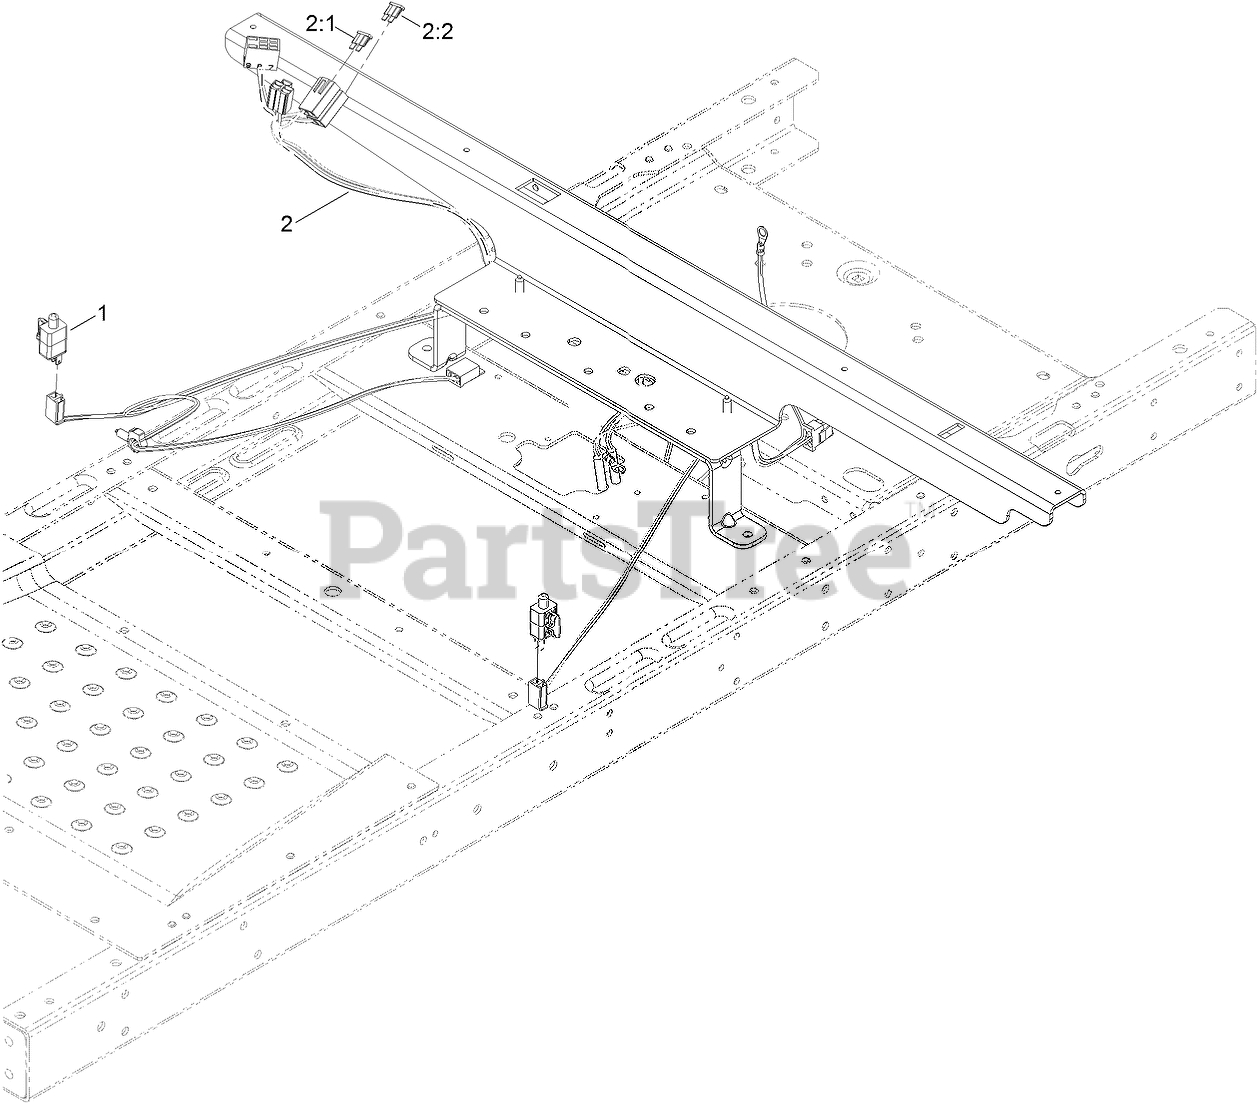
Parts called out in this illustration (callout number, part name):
1	SWITCH
2	HARNESS-WIRE
2:1	FUSE-BLADE, 30 AMP
2:2	FUSE-BLADE, 25 AMP
